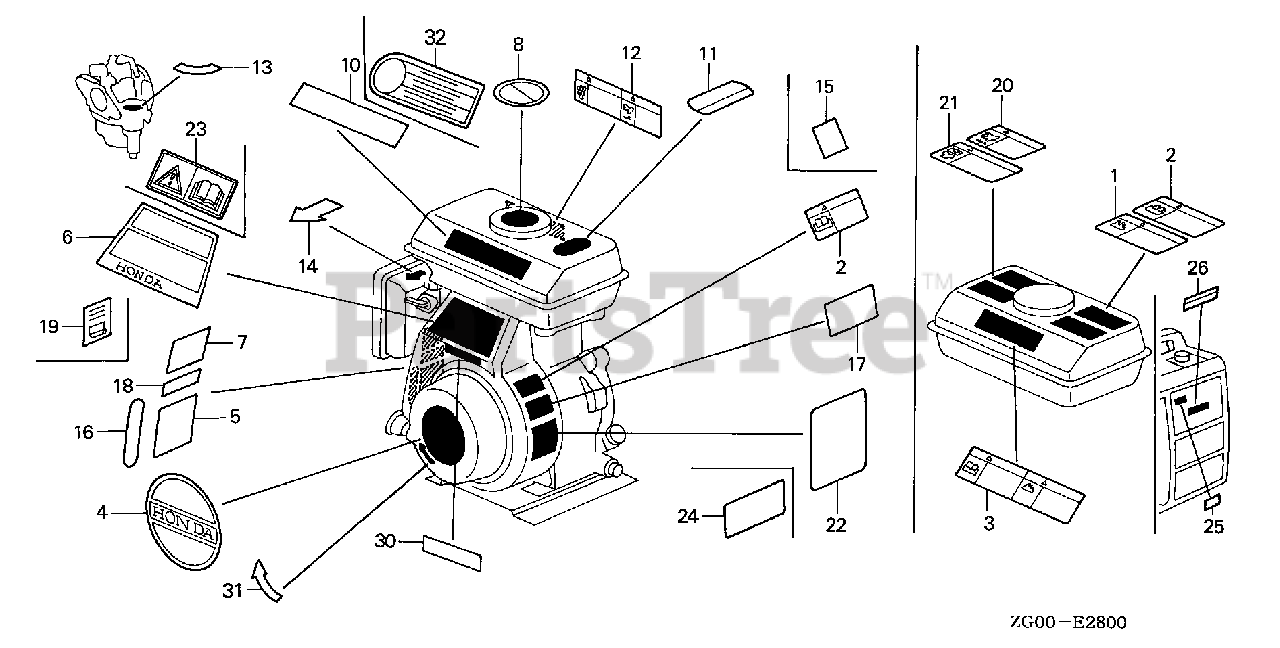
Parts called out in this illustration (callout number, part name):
4	EMBLEM (EXP)
8	MARK, CAUTION (EXTERNAL)
13	MARK (EXTERNAL)
14	MARK, CHOKE
16	MARK, THROTTLE (ENGLISH/FRENCH)(GERMAN)
